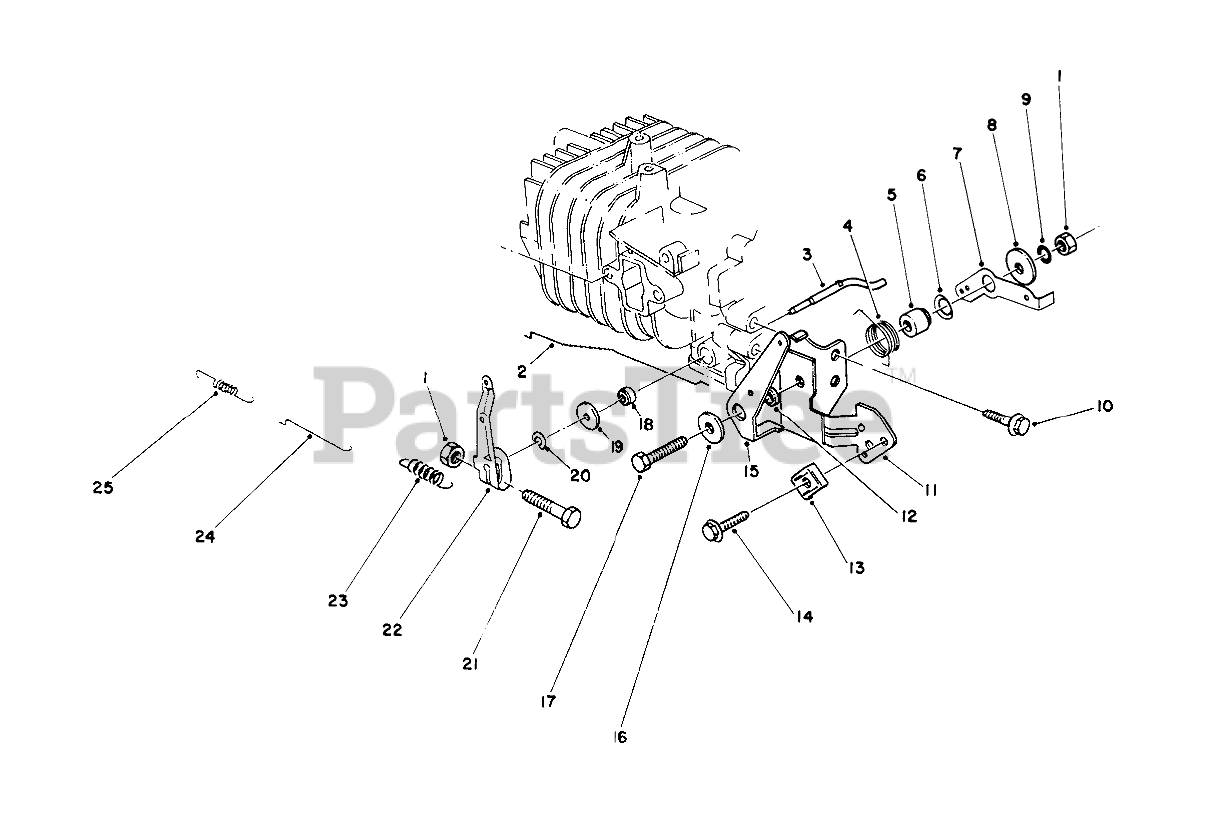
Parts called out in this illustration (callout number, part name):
2	CHOKE ROD
3	Shaft-Govemor
4	SPRING-CHOKE LEVER
5	Gov Lever Spacer
6	Washer-Gov. Spring Lever
7	GOV SPRING LEVER
8	WASHER
9	LOCKWASHER
11	BRACKET-THROTTLE, CONTROL
12	SPACER-CHOKE LEVER
13	CLAMP
15	LEVER-CONTROL, CHOKE
16	WASHER
18	SEAL-OIL
19	WASHER
20	E-RING
22	Lever-Throttle Control
23	GOVERNOR SPRING
24	ROD-CARBURETOR
25	SPRING
